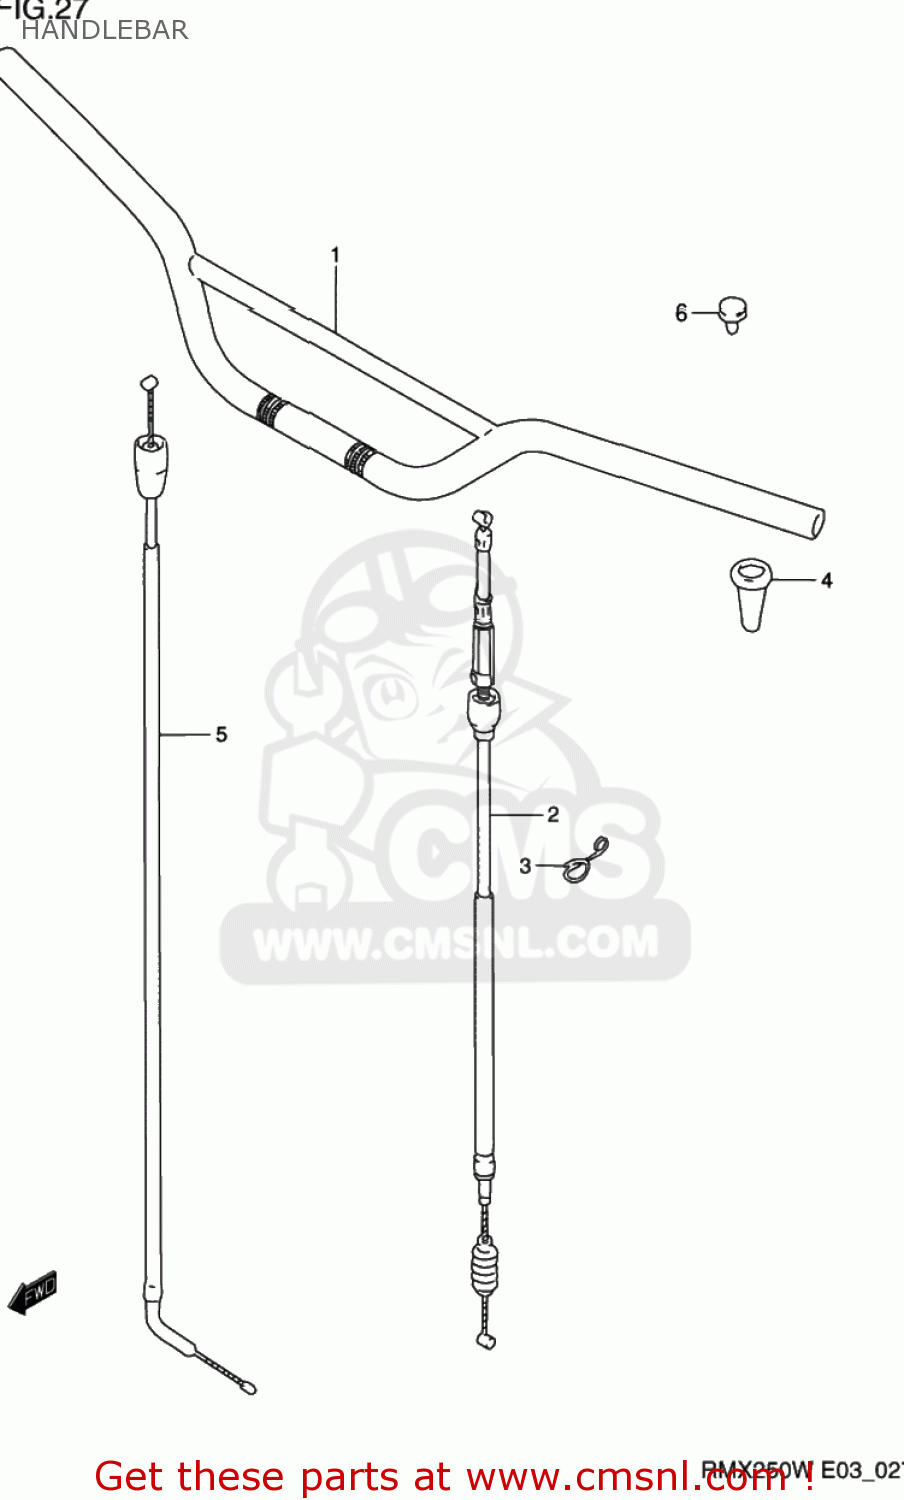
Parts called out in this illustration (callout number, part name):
1	HANDLEBAR
2	CABLE ASSEMBLY,CLUTCH
3	CLAMP,CLUTCH CABLE NO
4	BOOT,CLUTCH CABLE
5	CABLE ASSY,THROTTLE
6	CAP(OD:14)
